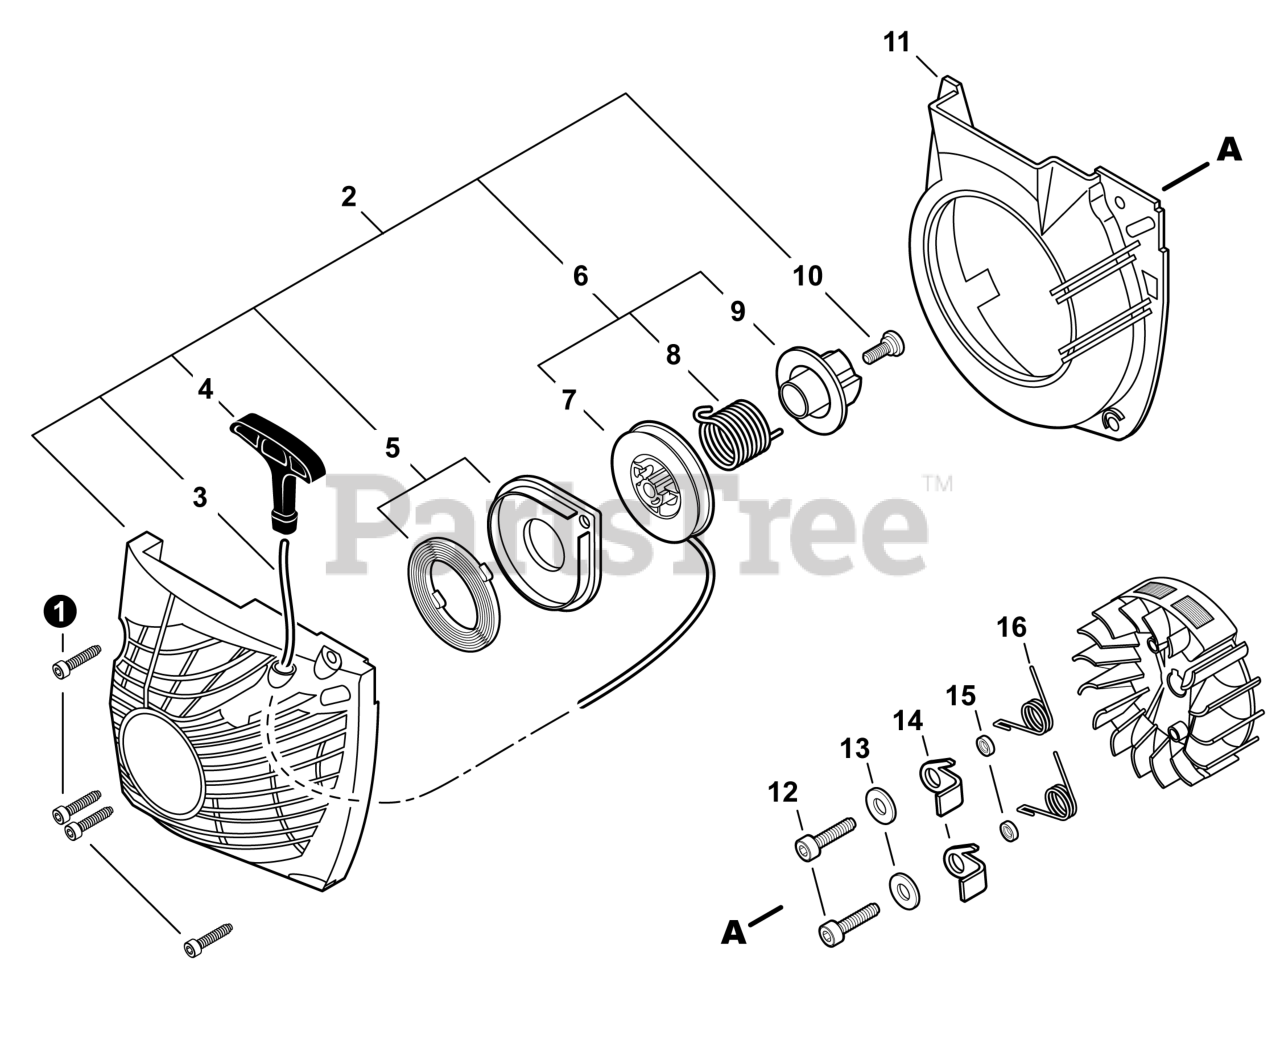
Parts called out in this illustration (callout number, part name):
1	BOLT 5x20
2	STARTER ASSY, RECOIL - I-START
3	ROPE, STARTER 3.5x900
4	GRIP, STARTER
5	SPRING SET, RECOIL
6	REEL KIT, ROPE
7	REEL, ROPE
8	SPRING, TORSION
9	PAWL CATCHER
10	SCREW 5
11	COVER, FAN
12	BOLT 5x14
13	WASHER 5.5x12x0.8
15	SPACER 5.2x8x2.1
16	SPRING, TORSION
